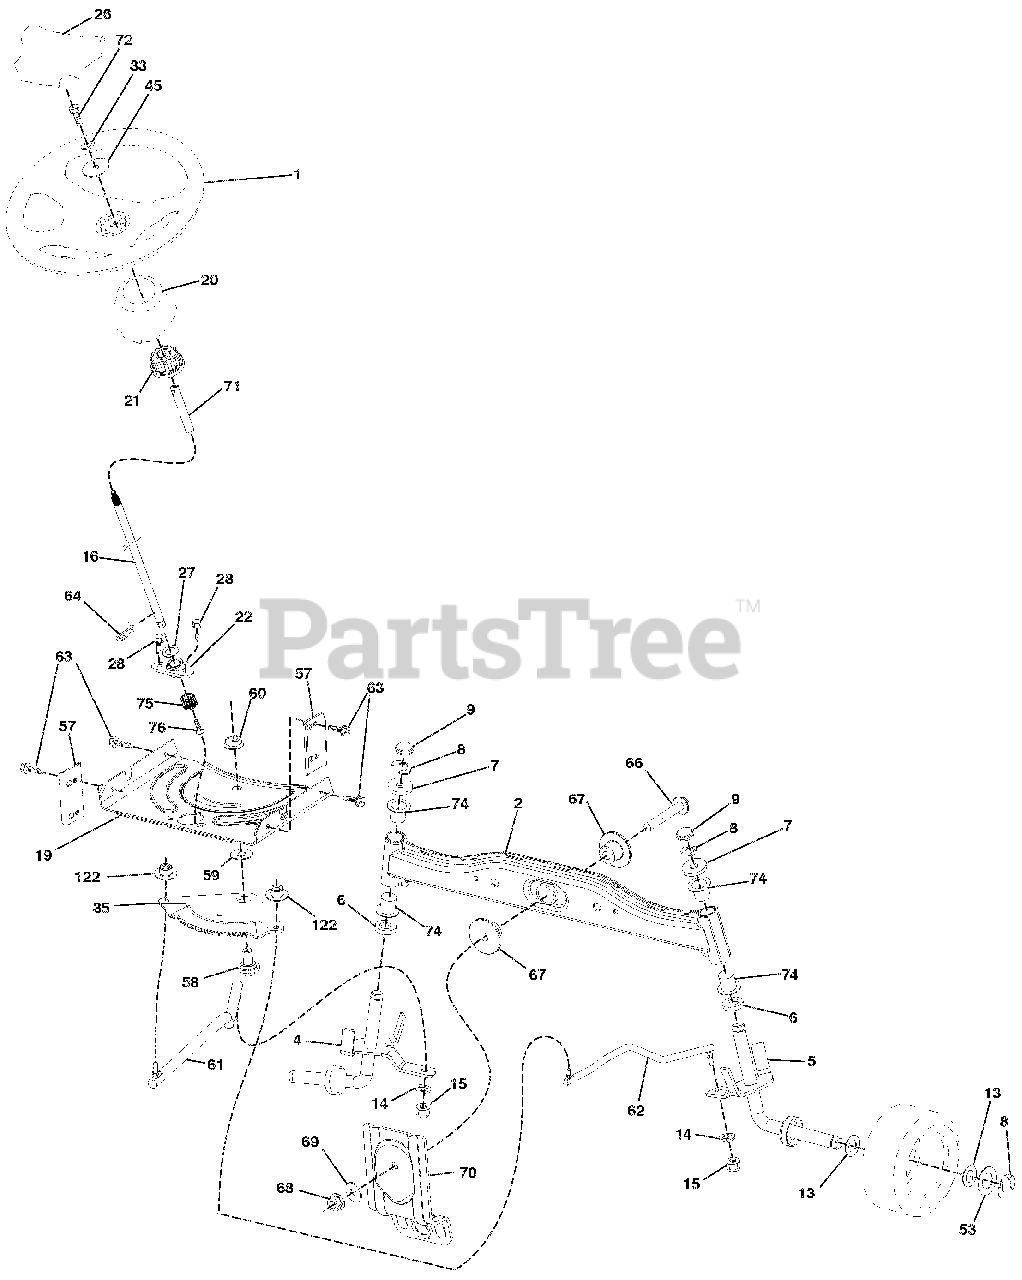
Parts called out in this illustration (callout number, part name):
1	WHEEL.STEERING.HARD RIM.BLACK
2	AXLE.CAST IRON
4	SPINDLE.WELDED.LH.15"TEX
5	SPINDLE.WELDED.RH.15"TEX
6	WAHSER THRUST .75 X 1.230
7	WASHER.25/32 X 1-5/8 X 16GA.
8	RING.KLIP.#T5304-75
9	CAP.SPINDLE.FR.TOP.BLK.
13	WASHER.25/32 X 1 1/4 X 16 GA.
14	Washer, Lock 3/8
15	NUT.CROWNLOCK.3/8-24
16	STEERING SHAFT
19	PLATE.STEER.DDL.NLT/NGT
20	BOOT.STEERING
21	ADAPTER.WHEEL.STRG..760
22	STEER.SUPT. LOWER
26	CAP WHEEL STEERING HRS/SRS BLK
27	Washer 21/32 x 1 x 16 Ga.
28	SCREW.HEXWSH THDR3/8-16X3/4.BL
33	Washer, Lock 5/16
35	GEAR SECTOR.PLATE.DDL.NLT/NGT
45	WASHER.11/32ID X2 3/8OD X 12GA
53	WASHER.HARDEN..793 X 1.637X060
57	BRACKET.UPSTOP.TEX
58	BOLT.SHOULDER.SECTOR.PIVOT.CFM
59	WASHER.THRUST.SECTOR.STEER.NLT
60	NUT.FLANGE LOCK.5/8-11
61	DRAGLINK.LH.BALLSTUD.DDL.
62	DRAGLINK.RH.BALLSTUD.DDL
63	SCREW.5/16-18X3/4.SMGML.TAP/BL
64	RETAINER.CLIP.SPRING.STEERING
66	BOLT.HEX.FGHD.7/16-14 X 3.SERR
67	BUSHING.PM.FRONT AXLE
68	NUT.LOCK.FLANGE.7/16-14.GR5
69	WASHER.1.5 X .505 X .118
70	BRACKET.DECK.SUSPENSION.FRONT
71	Extension Steering
72	Bolt 5/16-18 x 14 w/Patch
74	BEARING COL STRNG BLK
75	PINION
122	CAP GEAR SECTOR
